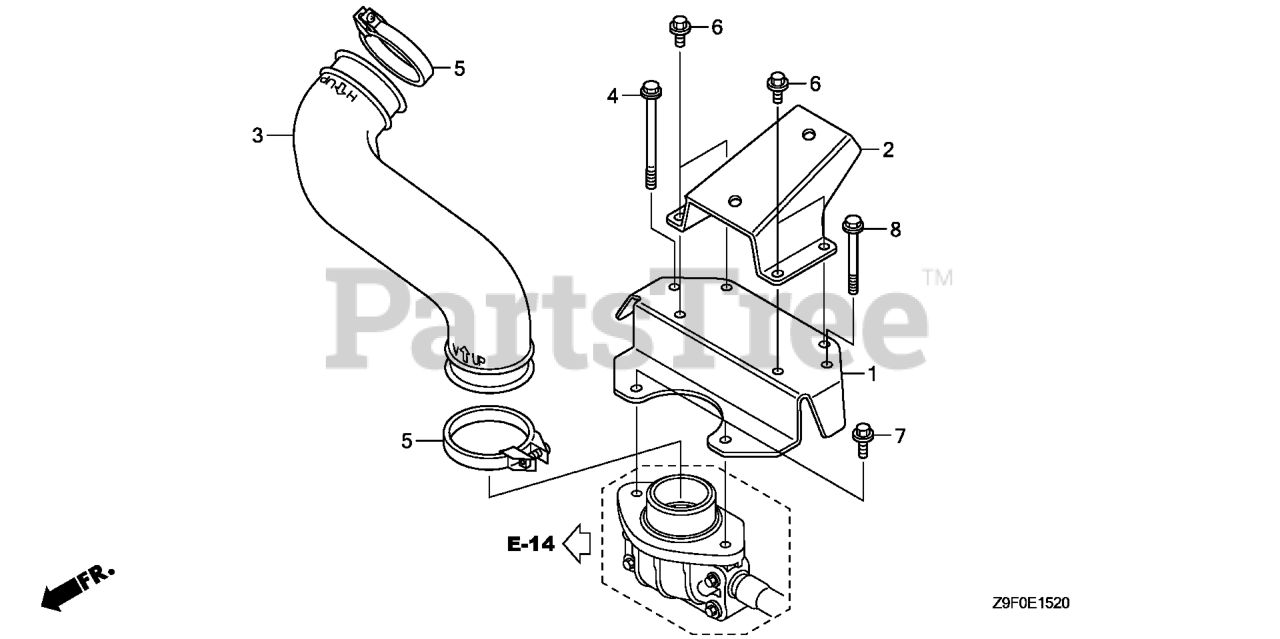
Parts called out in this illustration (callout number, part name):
1	STAY, AIR CLEANER
2	SUB-STAY, AIR CLEANER
3	TUBE, AIR CLEANER CONNECTING
4	BOLT, FLANGE (6X83)
5	BAND, AIR CLEANER CONNECTING TUBE (58)
6	BOLT, FLANGE (6X10)
7	BOLT, FLANGE (6X14)
8	BOLT, FLANGE (6X50)
